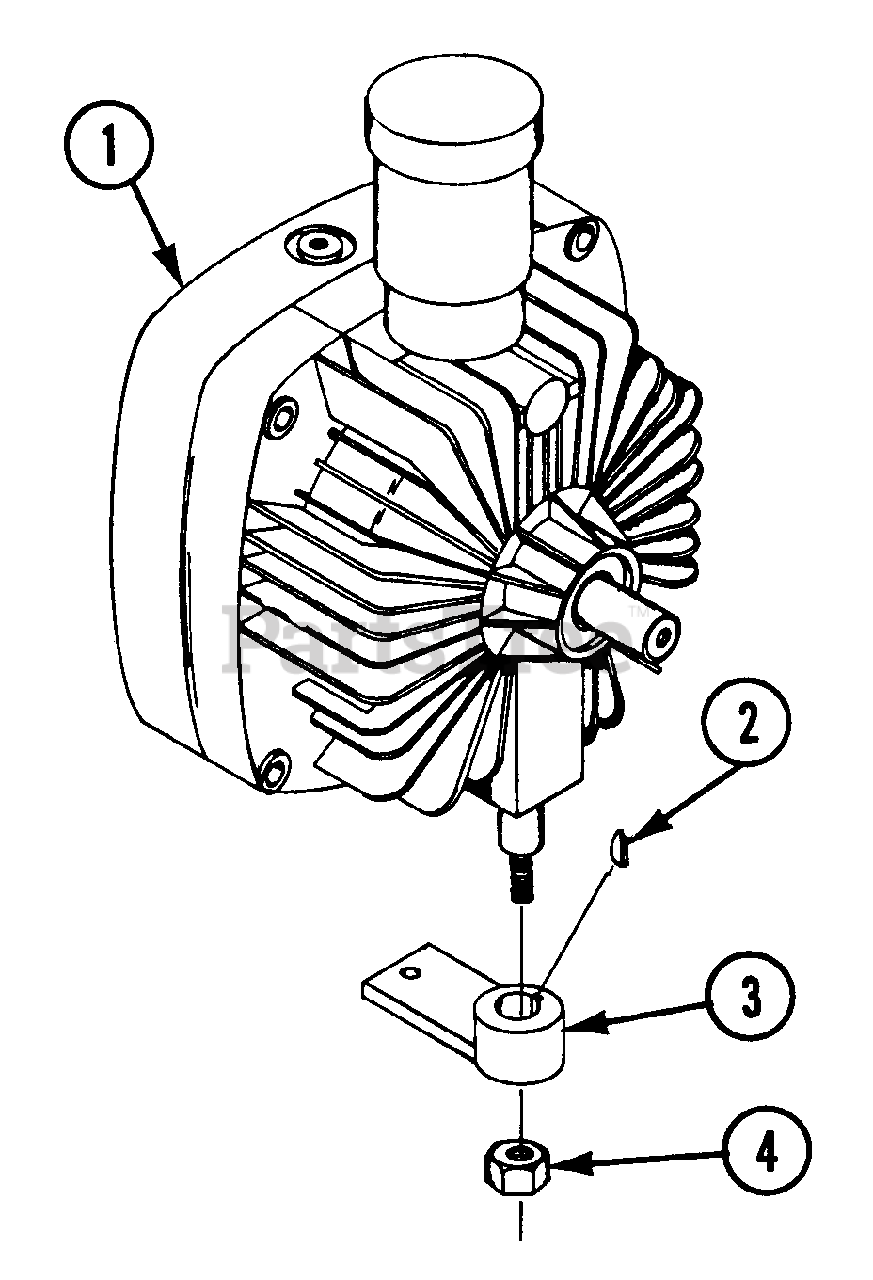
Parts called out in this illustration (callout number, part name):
1	EATON HYDRO #700-011 (RIGHT SIDE)
1	EATON HYDRO #780-003 (LEFT SIDE)
2	WOODRUFF KEYS 1/8 X 1/2
3	HYDRO SWIVEL MOUNT WELDMENT
4	LOCKNUT, HEX, 3/8-16 W/NYLOC
